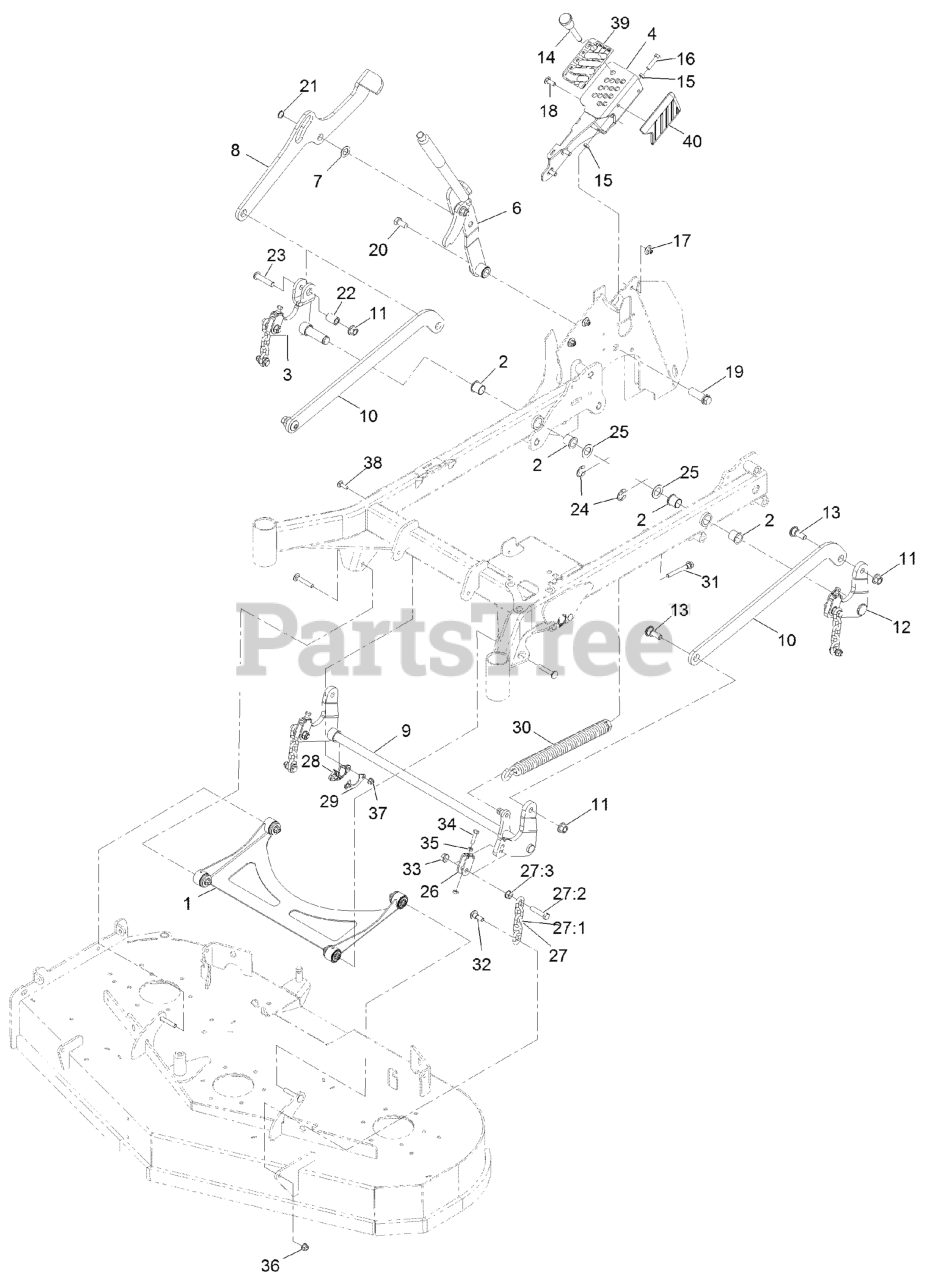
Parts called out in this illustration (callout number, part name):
2	BUSHING, IGUS
3	WELD, BELLCRANK, RT
7	WASHER-THRUST
9	WELD, HOC CROSS SHAFT
10	STRAP, HOC LIFT
11	Nut-Lock 1/2-13
12	WELD, BELLCRANK
13	BOLT, SHOULDER
14	PIN-HOC
15	NUT-JAM
16	BOLT-HH
17	Nut-Nyloc 3/8-16 Flg
18	SCREW-CARR
19	HUB-THREADED
20	SCREW-HH
21	RING-SNAP
22	SPACER, HOC
23	SCREW-HSBH
24	RING-RETAINING, EXT
25	Washer-Flat
26	YOKE-ADJUST, DECK
27	DECK LIFT CHAIN ASM
27:1	CHAIN-LIFT, DECK
27:2	SCREW-HH
28	BUSHING-FLANGE
29	GUSSET-LIFT, DECK
30	SPRING-EXTENSION
31	BOLT-SHOULDER
32	SCREW-SHOULDER, HHF
34	SCREW-HH
35	NUT-JAM
36	NUT-HF, NI
37	NUT-HF, NI
38	BOLT-CARR
39	DECAL-HEIGHT OF CUT
40	PAD, KNEE
